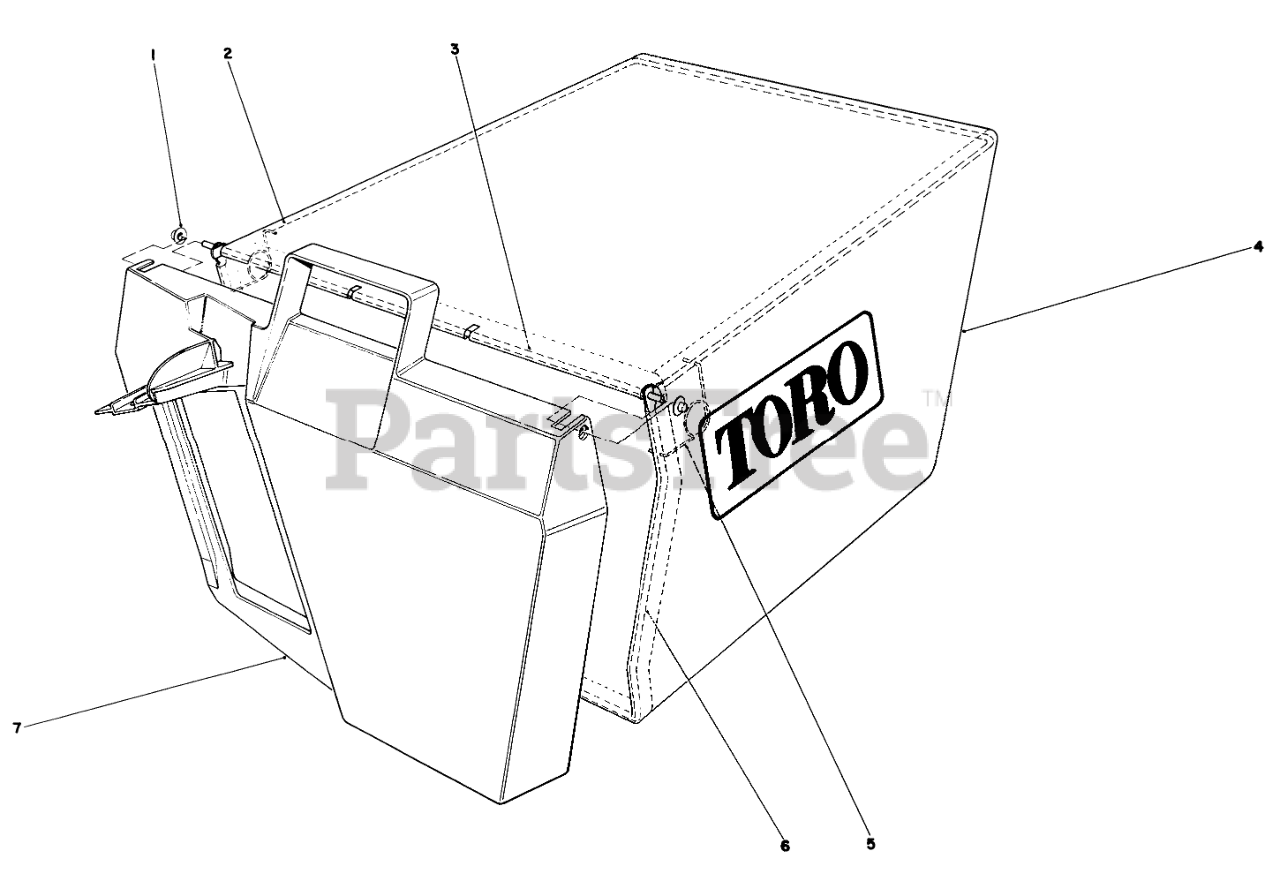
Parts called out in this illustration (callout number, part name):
1	NUT-PUSH
2	FRAME-BAG, UPPER
3	HINGE-DOOR, BAG
4	Bag
5	SPRING
6	BAG FRAME
7	Door Grass Bag
